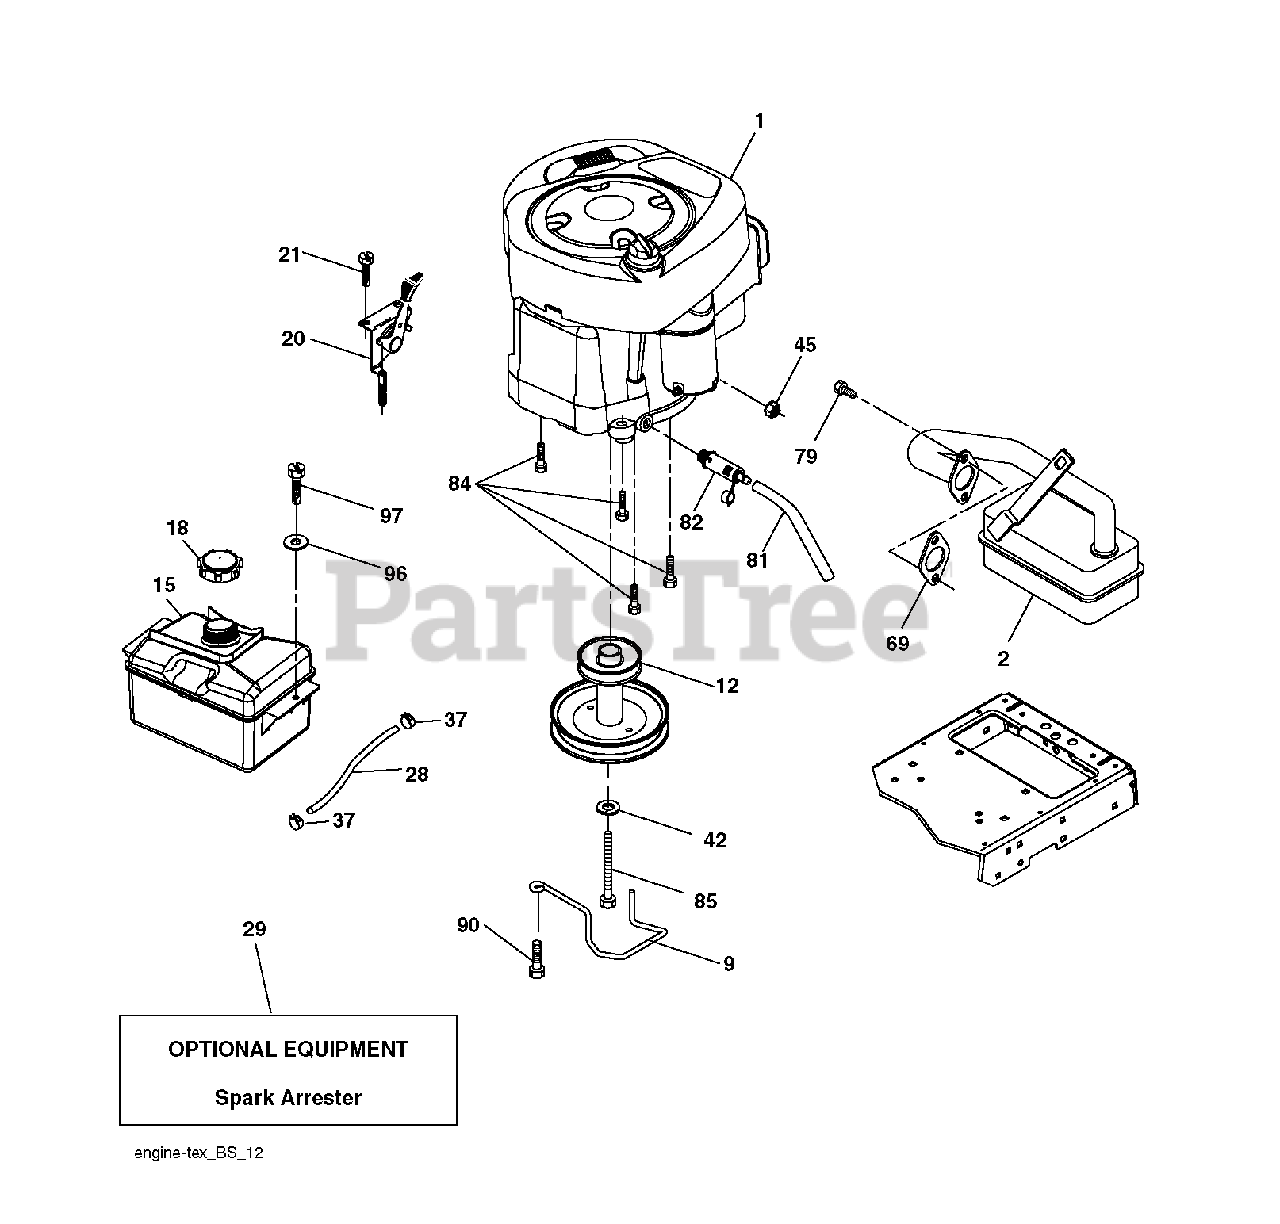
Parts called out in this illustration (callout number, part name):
2	MUFFLER.LT.BRIGGS.14HP.IC/OHV
9	KEEPER.BELT.ENGINE.4.2
12	PULLY ENGINE
15	RP TANK FUEL FRT 1.5 GAL
18	FUEL CAP
21	SCREW.#10 X 0.750.BOS (2 2)
28	LINE.FUEL.20
29	KIT.SPARK ARRESTOR(392390 B&S)
37	HOSE CLAMP
42	LOCKWASHER
45	NUT
79	SCREW.SOCKET HD.5/16-1
81	TUBE, DRAIN OIL ASM.
82	PLUG DRAIN OIL EASY
84	SCREW.3/8-16
85	BOLT HEX 7/16-20X4-1/4"
90	SCREW 3/8-16X1
96	WASHER
97	SCREW HEXWSHR 1/4-20X3/4
